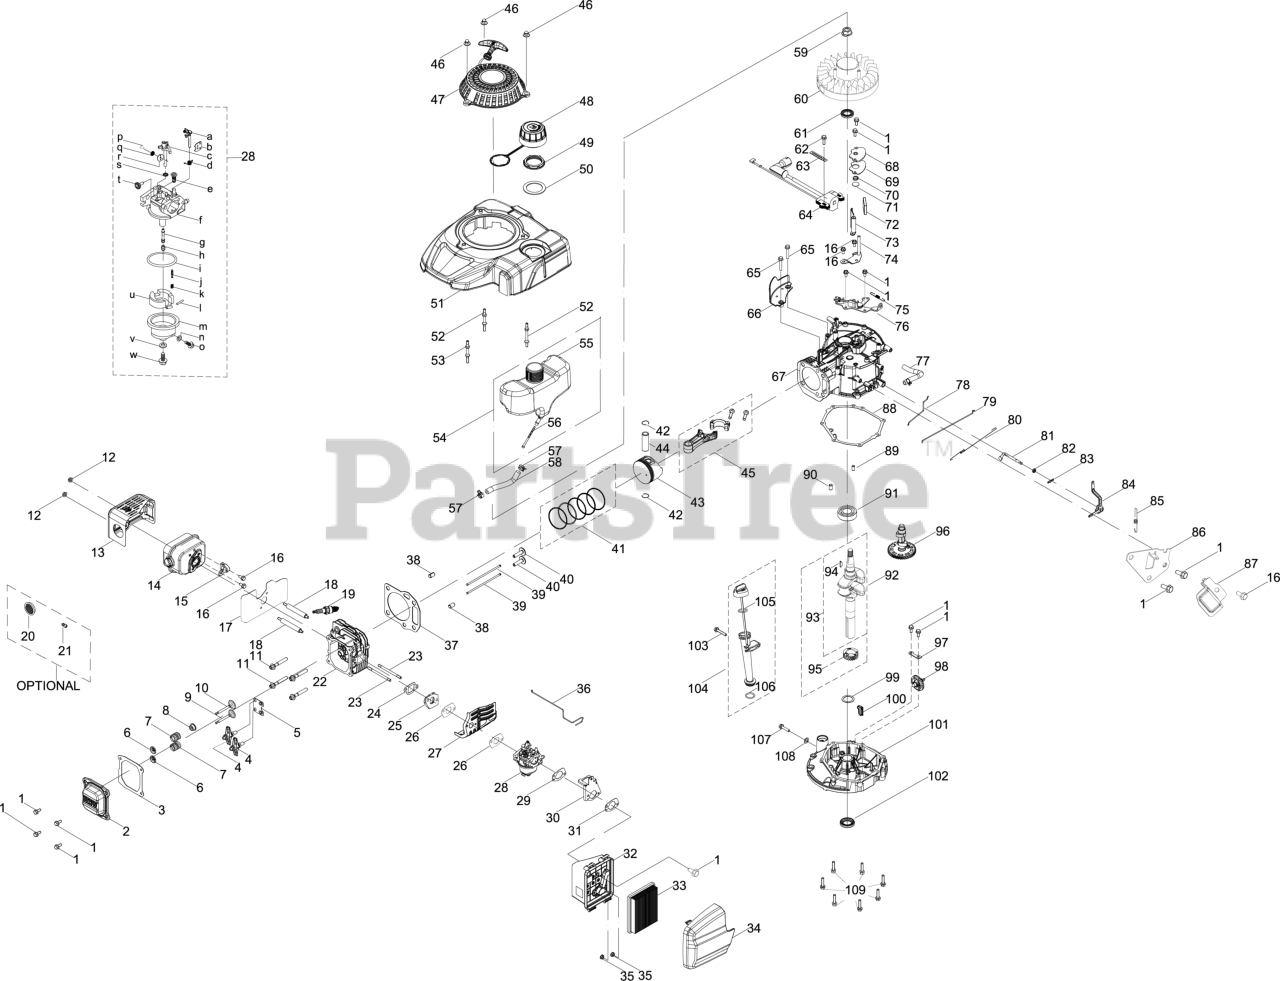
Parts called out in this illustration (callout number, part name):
1	BOLT M6-1 x 14 GR8.8
2	VALVE COVER
3	VALVE COVER GASKET
4	ROCKER ARM
5	PUSH ROD GUIDE
6	VALVE RETURN SPRING
7	VALVE SPRING
8	INTAKE VALVE SEAL
9	EXHAUST VALVE
10	INTAKE VALVE
11	BOLT-M8 x 54
12	HEX NUT
13	MUFFLER SHIELD
14	MUFFLER ASSEMBLY
15	THERMOSTAT
16	BOLT M6-1 x 12 GR8.8
17	MUFFLER GASKET
18	STUD M6-1 x 95
19	SPARK PLUG (F5RTC/RN11YC4/BPR5ES)
19	Cub Cadet SPARK PLUG-F5RTC
19	Genuine Factory Parts SPARK PLUG (14437)
20	SPARK ARRESTOR
21	SCREW M3.5 x 9.5
22	CYLINDER HEAD
23	STUD M6 x 90
24	CARBURETOR INSULATOR GASKET
25	CARBURETOR INSULATOR
26	CARBURETOR GASKET
27	CARBURETOR HEAT SHIELD
28	CARBURETOR
29	AIR FILTER BRACKET GASKET
30	AIR FILTER BRACKET
31	AIR FILTER BASE GASKET
32	AIR FILTER BASE
33	AIR FILTER
34	AIR FILTER COVER
35	HEX NUT
36	CHOKE TEMP CONTROL LINKAGE
37	CYLINDER HEAD GASKET
38	PIN (10MMx16MM)
39	PUSH ROD
41	PISTON RING SET
42	WRIST PIN CLIP
43	PISTION
44	PISTON PIN
45	CONNECTING ROD ASSEMBLY
46	ACORN NUT M6-1
47	RECOIL STARTER ASSEMBLY
48	FUEL CAP W/TETHER
49	FUEL TANK NUT
50	FUEL TANK GROMMET
51	ENGINE SHROUD W/O IGNITION SWITCH
52	STARTER/SHROUD REAR STUD
53	STARTER/SHROUD FRONT STUD
55	FUEL TANK
56	FUEL FILTER
57	CARBURETOR HOSE CLAMP
58	FUEL HOSE
59	FLYWHEEL NUT M14-1.5
60	FLYWHEEL
61	UPPER CRANKSHAFT SEAL
62	BOLT M6-1 x 20 GR8.8
63	FLEXIBLE CLAMP
64	IGNITION COIL ASSEMBLY
65	BOLT M6-1 x 25 GR8.8
66	ENGINE BRAKE COVER PLATE
67	CRANKCASE
68	BREATHER COVER PLATE
69	BREATHER GASKET
70	BREATHER VALVE SPRING
71	BREATHER VALVE
72	BREATHER SCREEN
73	AIR VANE
74	AIR VANE BRACKET
75	ENGINE BRAKE SPRING
76	ENGINE BRAKE ASSEMBLY
77	BREATHER HOSE ASSEMBLY
78	CHOKE LINKAGE
79	THROTTLE LINKAGE
80	THROTTLE LINKAGE SPRING
81	GOVERNOR ARM SHAFT
82	OIL SEAL
83	COTTER PIN
84	GOVERNOR ARM ASSEMBLY
85	GOVERNOR SPRING
86	COMPONENT BRACKET
87	GOVERNOR SHIELD
88	CRANKCASE COVER GASKET
89	DOWEL PIN 7 X 14
90	DOWEL PIN 9 X 14
91	BEARING
92	CRANKSHAFT ASSEMBLY
93	CRANKSHAFT
94	WOODRUFF KEY
96	CAMSHAFT
97	GOVERNOR GEAR MOUNTING PLATE
98	GEAR GOVERNOR
99	THRUST WASHER
100	OIL RETURN SEAL
101	CRANKCASE COVER
102	LOWER CRANKSHAFT SEAL
103	BOLT M6-1 x 35 GR8.8
104	OIL DIPSTICK ASSEMBLY
107	OIL DRAIN PLUG
108	FLAT WASHER
109	BOLT-M6-1 x 28 GR8.8
S	CARB SHAFT GASKET
